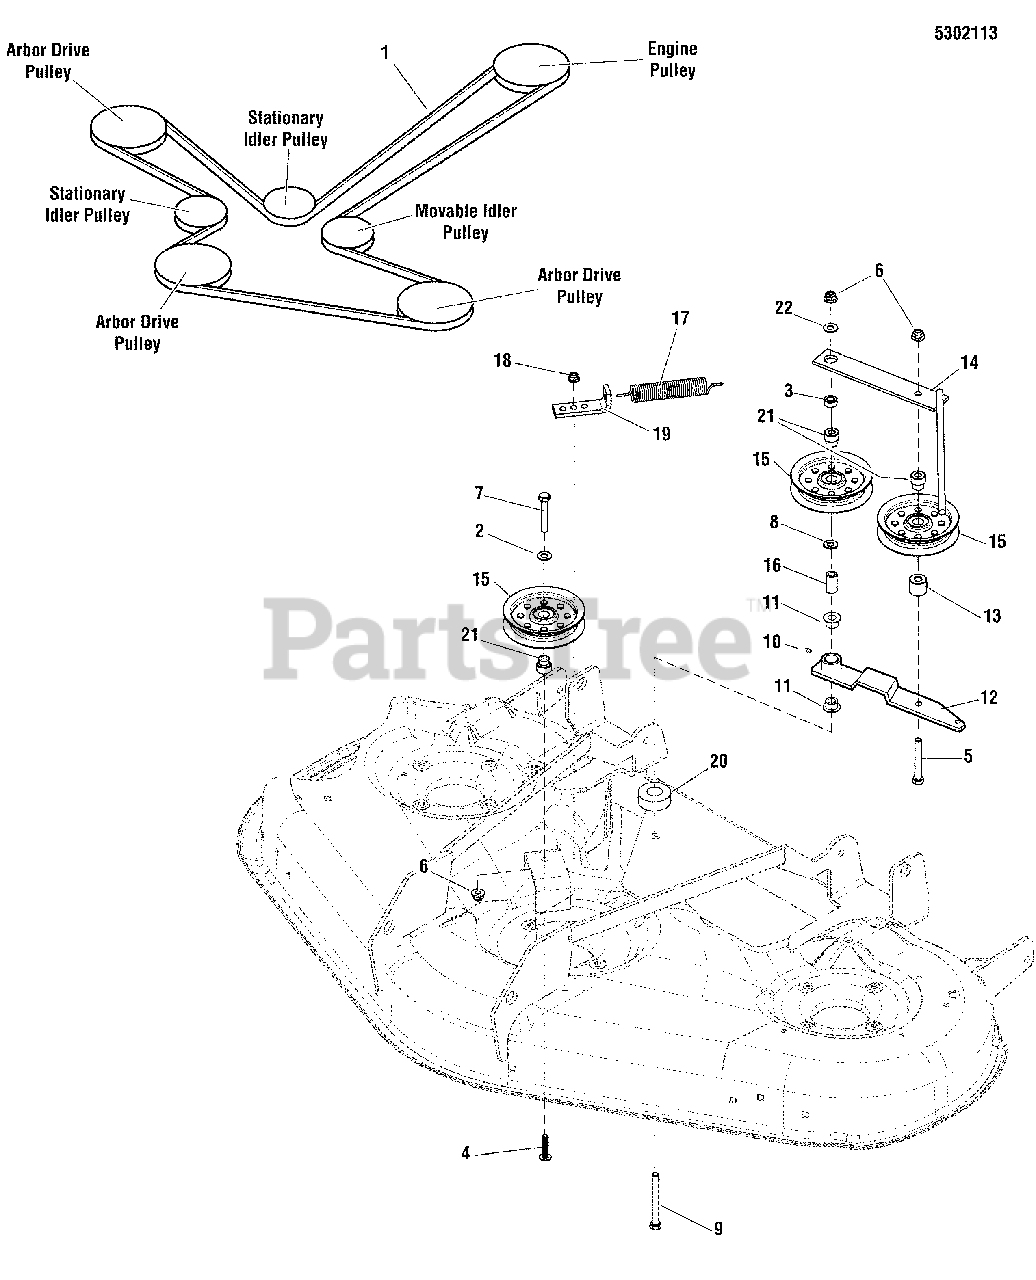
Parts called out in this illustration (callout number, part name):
1	BELT HA-SEC 158.00
2	WASHER, 3/8" USS
3	SPACER, .39 X .75 X .38, PM, CZ
4	SCREW-HEX WSHR HD TAPTT5/16-18X1.000BLK
5	BOLT, 3/8-16 X 2-3/4" GD5 CZ
6	NUT, 3/8 - 16 HEX NYLOCK FLANGE
7	BOLT, 3/8-16 X 2, GD5, CZ
8	WASHER, 3/8 SAE
9	BOLT, 3/8-16 X 4" GD5 CZ
10	GREASE FITTING, 1/4-28 Straight
11	BUSHING-0.628IDX0.751ODX0.400LG PWDR MTL
12	WELD, DECK IDLER ARM, CONSZ - RED
13	SPACER, .39 X 1.00 X .88, CZ
14	WELD, MOUNT, IDLER TENSION - RED
15	PULLEY, Backside Idler
16	SPACER-0.39 IDX0.625ODX1.15 LG CASE HARD
17	SPRING, EXTENSION, 1.00
18	NUT, Hex Flange Whiz Lock, 5/16-18 all Black
19	BRACKET, SPRING ANCHOR - RED
20	SPACER, .39 X 1.75 X .63, YZ
21	SPACER, HYDRO PULLEY
22	WASHER, 5/16" USS
